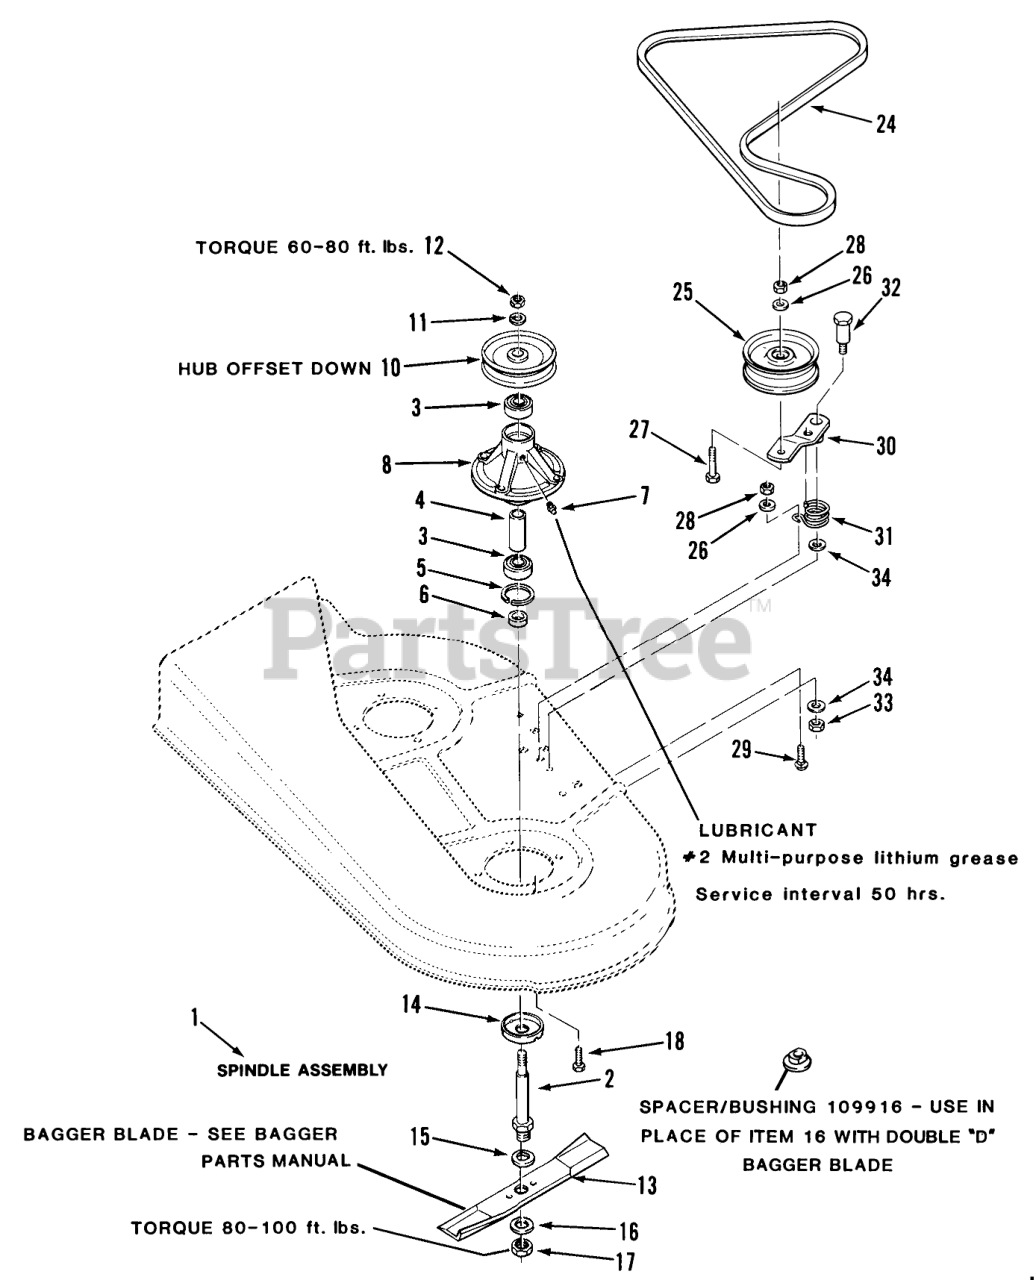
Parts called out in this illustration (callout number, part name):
1	Spindle Assembly, Metric Bearings (Includes Items 2 through 8, 14)
2	SHAFT SPINDLE
3	BEARING-BALL
5	Ring-Snap
6	SPACER-BLADE
7	Fitting-Grease
8	HOUSING SPINDLE
10	PULLEY BLADE
10	Pulley LH-4 3/4 O.D. (Deep Groove)
11	Lockwasher
12	Jam Nut
13	ASSY BLADE KIT
14	CUP-SPINDLE
15	Washer
16	SpeciaI Washer
17	Nut-Jam
18	Bolt
24	V-BELT
25	PULLEY-IDLER
26	Washer
27	Bolt
28	Nut
29	Bolt
30	Idler Arm
31	SPRING-TORSION
32	BOLT-SHOULDER
33	NUT-JAM(7/16-14)
34	WASHER
